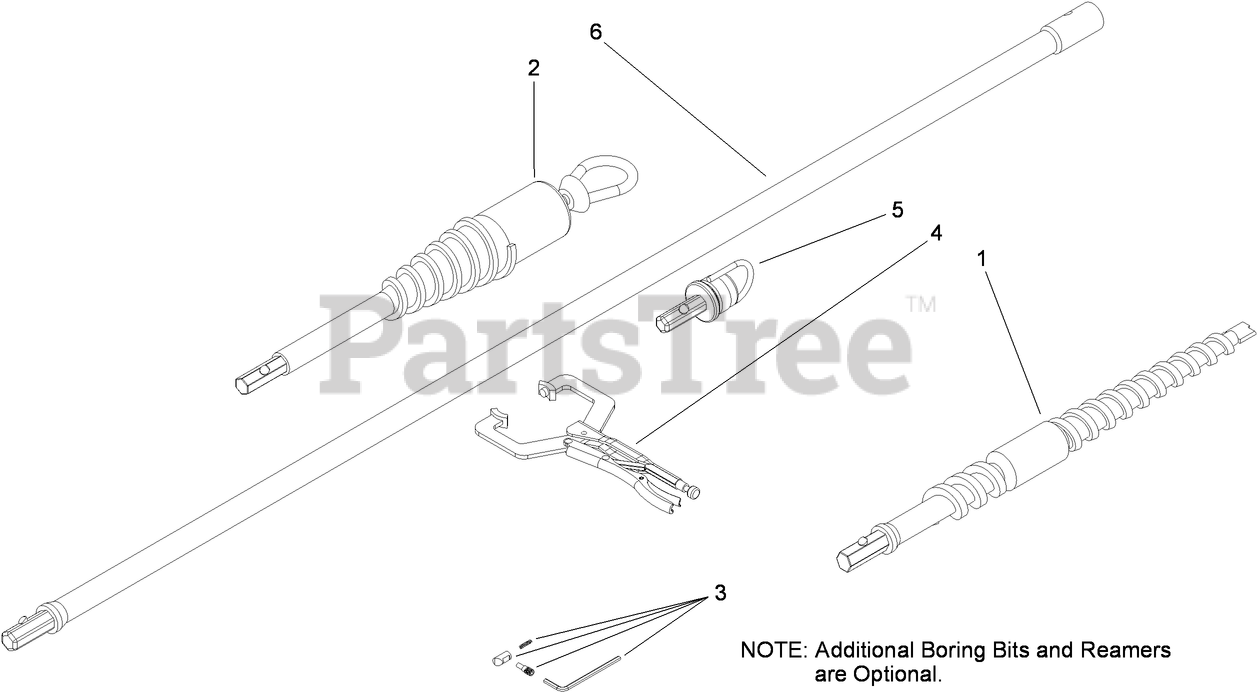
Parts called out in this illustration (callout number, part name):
1	BIT-BORING, 1-1/4 INCH
1	BIT-BORING, 1-7/16 INCH
1	BIT-BORING, 2 INCH
1	BIT-BORING, 2-1/2 INCH
1	BIT-BORING, 1-3/4 INCH
2	REAMER-2 INCH
2	REAMER, 2-7/8 INCH
2	REAMER, 3-1/4 INCH
2	REAMER, 3-1/2 INCH
2	REAMER, 4-1/2 INCH
2	REAMER, 2-1/2 INCH
3	REPAIR KIT
4	TOOL-UNCOUPLING
5	SHANK-SWIVEL
6	ROD-DRILL, 60 INCH
